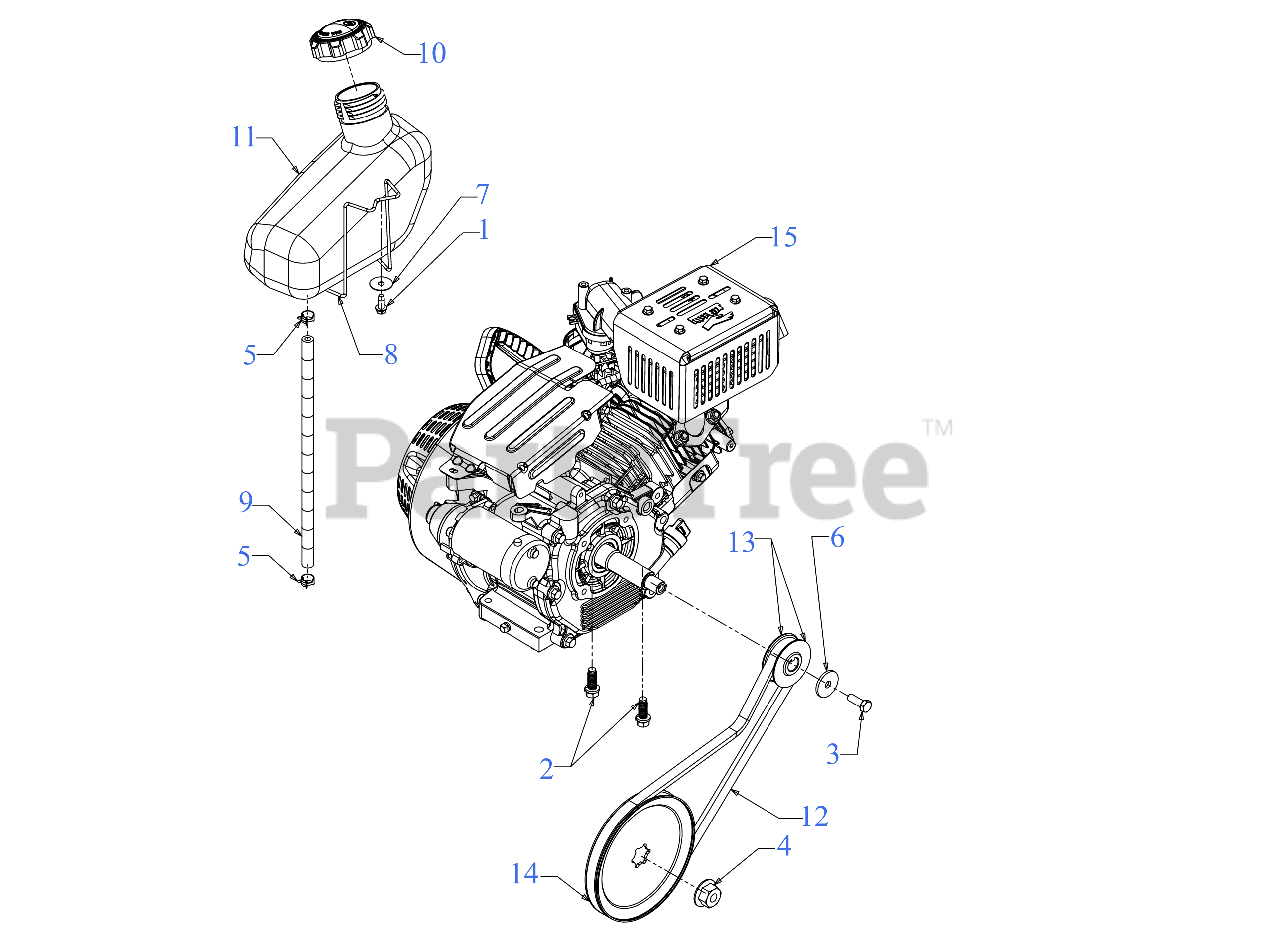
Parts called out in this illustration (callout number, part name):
1	SCREW 1/4-10:.625
2	SCREW 3/8-16 x 1
3	SCREW 5/16-24 x .875 GR5
4	FLANGE NUT W/HUB
5	HOSE CLAMP 1/20
6	WASHER-5/16 x 1.25X 1.27
7	FLAT WASHER
8	SUPPORT WIRE
9	FUEL HOSE LOW PERMEATION 13"
10	FUEL CAP
11	FUEL TANK (2 QT)
12	V-BELT .500 x 35.00LG
13	HALF PULLEY
14	AUGER PULLEY
15	COMPLETE ENGINE 123cc
